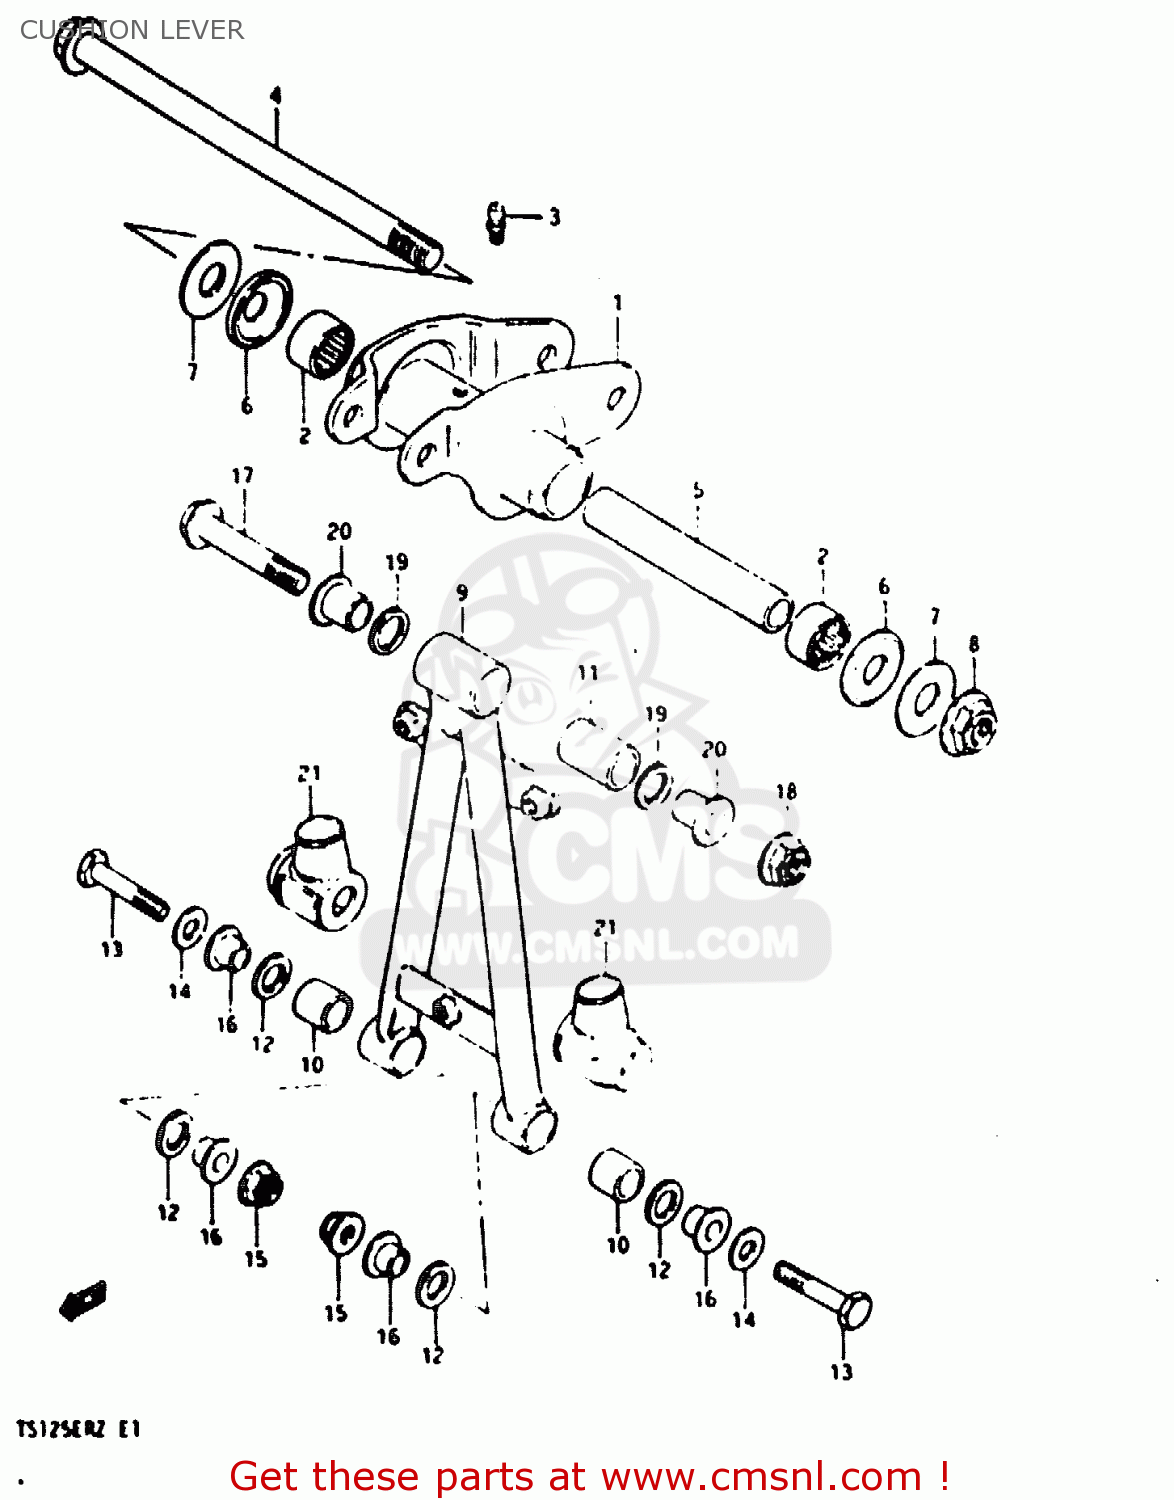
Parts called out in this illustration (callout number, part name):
1	LEVER ASSEMBLY,REAR CUSHION
2	BEARING(17X25X20)
3	GREASE NIPPLE
4	SHAFT,RR CUSHION LEVER
5	SPACER,REAR CUSHION LEVER
6	DUST SEAL,REAR CUSHION,LEFT
7	WASHER
8	NUT 12MM
9	ROD, CUSHION, LEVER
10	BUSHING
11	BUSH,UPPER
12	DUST SEAL,RR CUSHION LOD LWR
13	BOLT,REAR CUSHION ROD
14	WASHER
15	NUT
16	SPACER,RR CUSHION ROD LWR
17	BOLT(10X65)
18	NUT
19	DUST SEAL,LEVER CUSHION UNIT
20	SPACER,RR CUSHION ROD UPR
21	BOOT,REAR CUSHION ROD,LOWER
